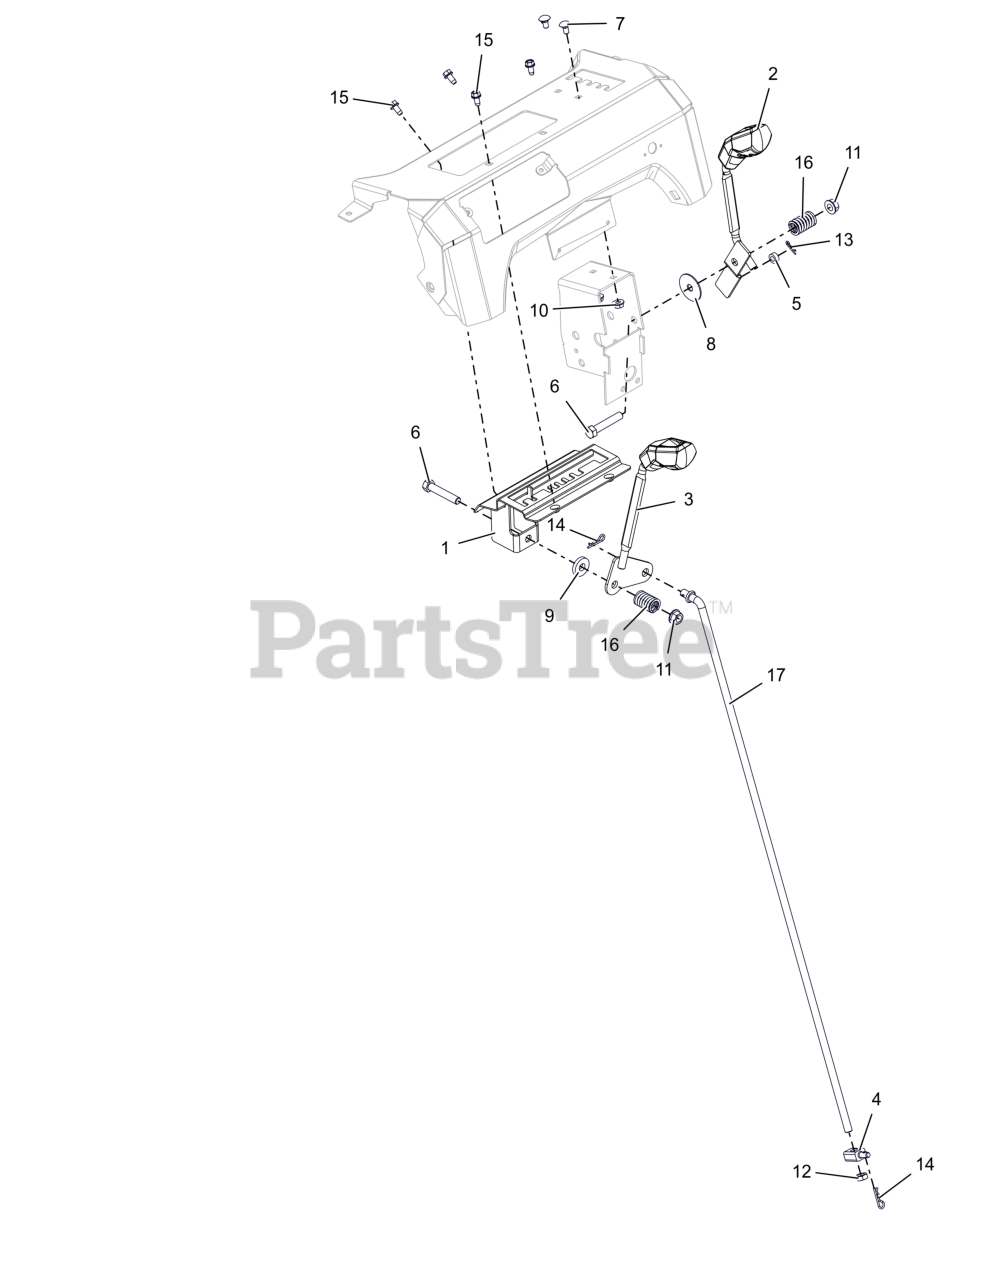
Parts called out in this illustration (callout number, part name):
1	WELDMENT, DETENT PLATE-COMPACT
2	ASM, LEVER W/KNOB-SM DASH DEFL
2	KNOB, CONTROL
3	ASM, LEVER W/KNOB-SM DASH SPEED
3	KNOB, CONTROL
4	PIVOT,SHIFT ROD .375-16(TRUNN)
5	BSHG-SLV .265X.500X.219
6	BLT,HEX .38-16X2.00 G5 ZCC
7	BLT, RHSN .25-20X.500 G5 ZCC
8	WSHR,FLT .380X1.50X.062 ZCC
9	WSHR, FLT .406X1.00X.188 ZCC
10	NUT-LK-CTR-FLG .25-20 ZC120
11	NUT-LK-TOP-FLG .38-16 ZC120
12	NUT-JAM .375-16 G2 ZCC
13	PIN, HAIR #178 .06X.77 ZCC
14	PIN, HAIR #213 .08X1.19 ZCC
15	SCR-TAP .25-20X.50 HWH ZCC
16	SG-COMP .125X.781X1.250
17	ROD, SHIFT - SMALL DASH DELUXE
